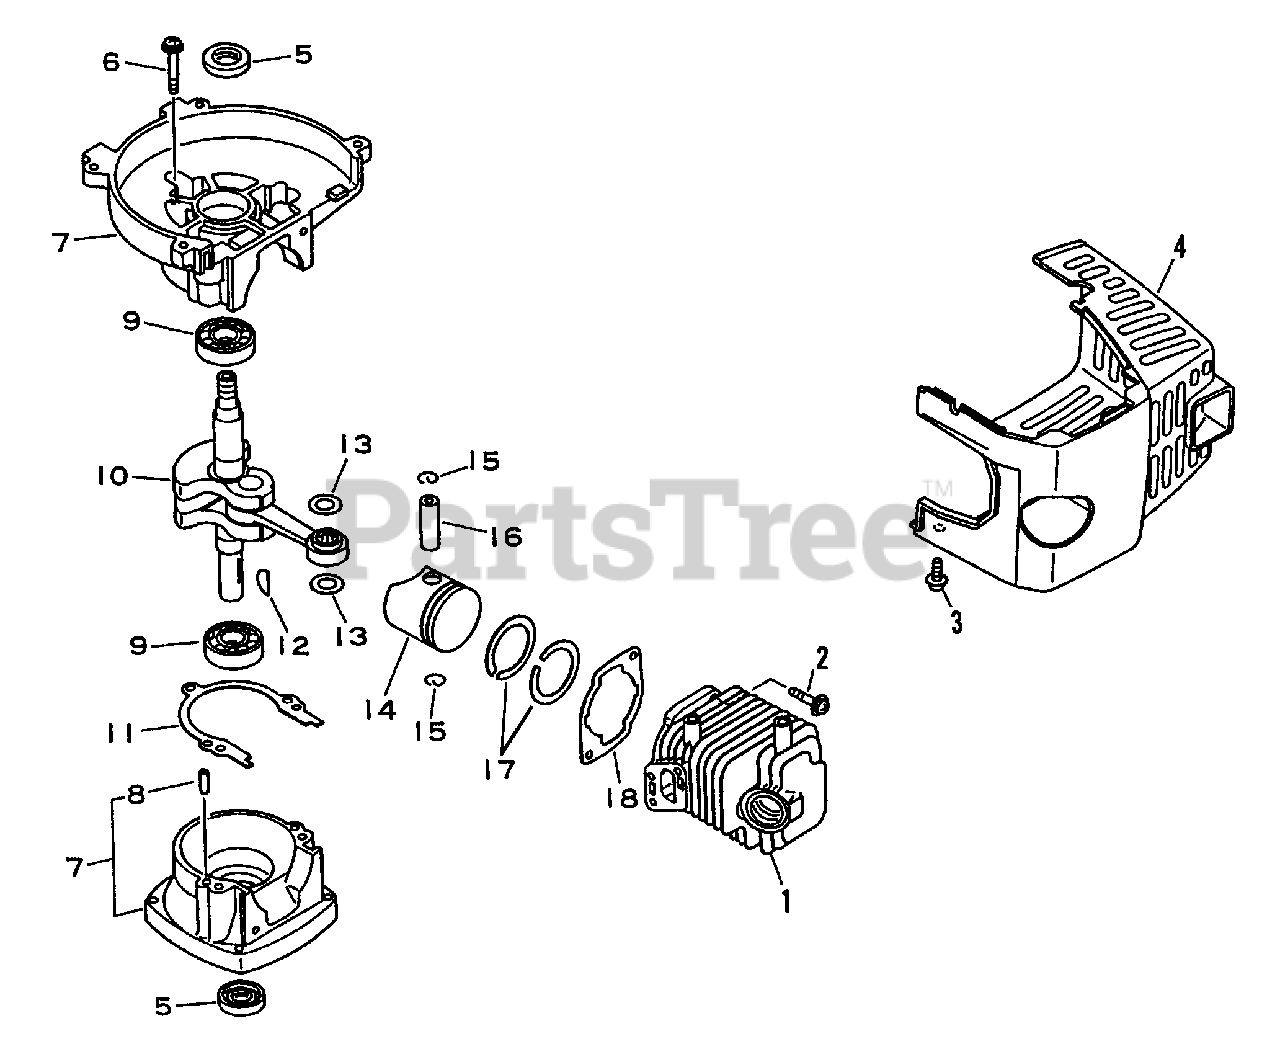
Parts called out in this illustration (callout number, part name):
1	CYLINDER
2	SCREW - 5X22
3	SCREW - 4X18
4	COVER, ENGINE
5	SEAL, OIL
6	SCREW - 5X28
7	CRANKCASE KIT
8	PIN - LOCATING
9	BEARING, BALL - 6201
10	CRANKSHAFT ASSY
11	GASKET, CRANKCASE
13	SPACER, PISTON
14	PISTON
15	RING, RETAINING
16	PIN, PISTON
17	RING, PISTON
18	GASKET, CYLINDER
19	BEARING, NEEDLE
